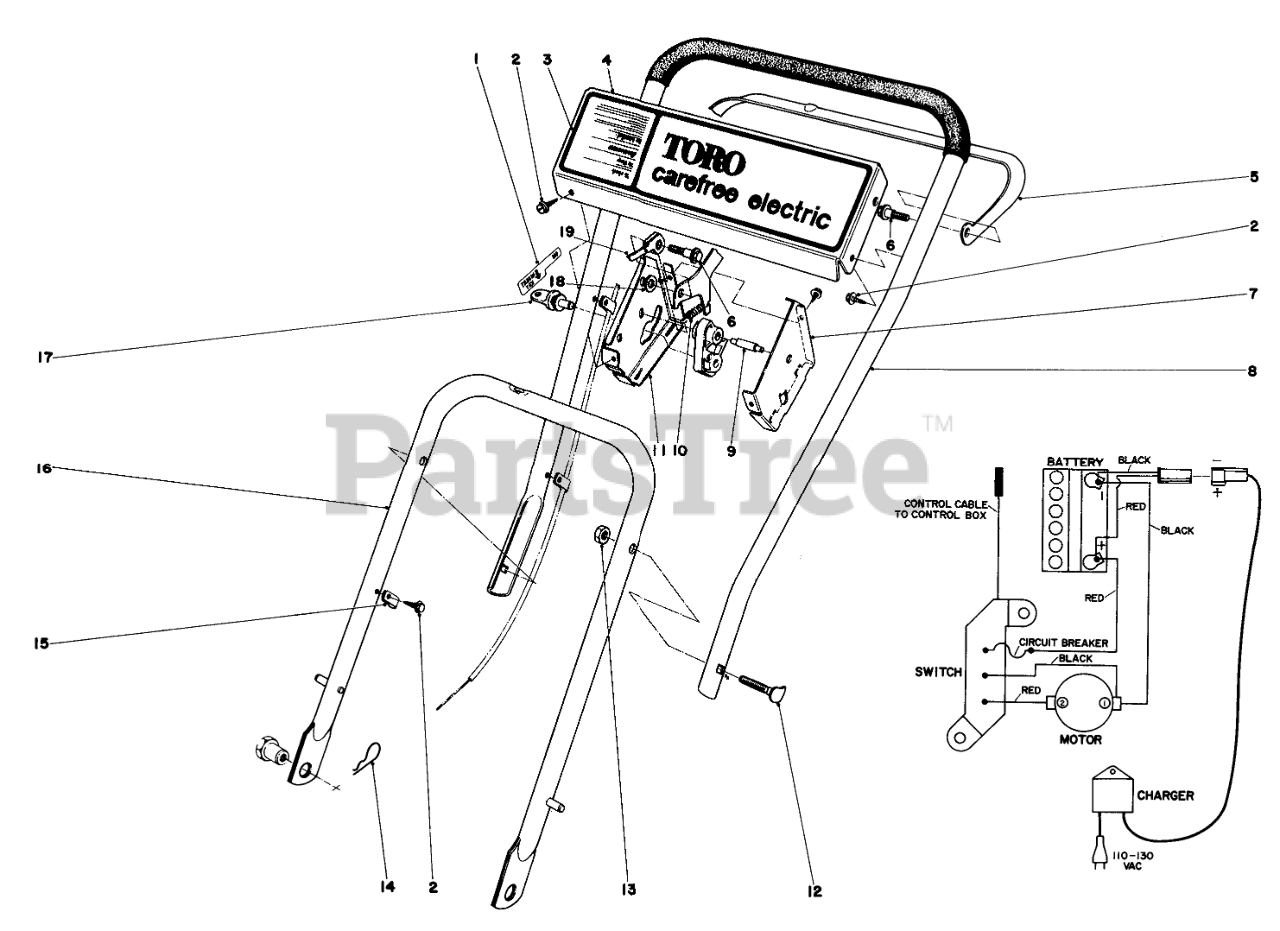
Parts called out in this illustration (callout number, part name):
1	Decal, Control Box
2	SCREW-HWHTF
3	Decal, Control Plate
4	Control Panel
5	Squeeze Lever
6	Shoulder Bolt
7	Cover Control Box
8	Upper Handle
9	Actuator Shaft
10	Spring Extension
11	Control Box
12	HANDLE SCREW
13	Nut
14	PIN-COTTER, HAIR
15	Clamp
16	Lower Handle
18	WASHER-FLAT
19	Latch
